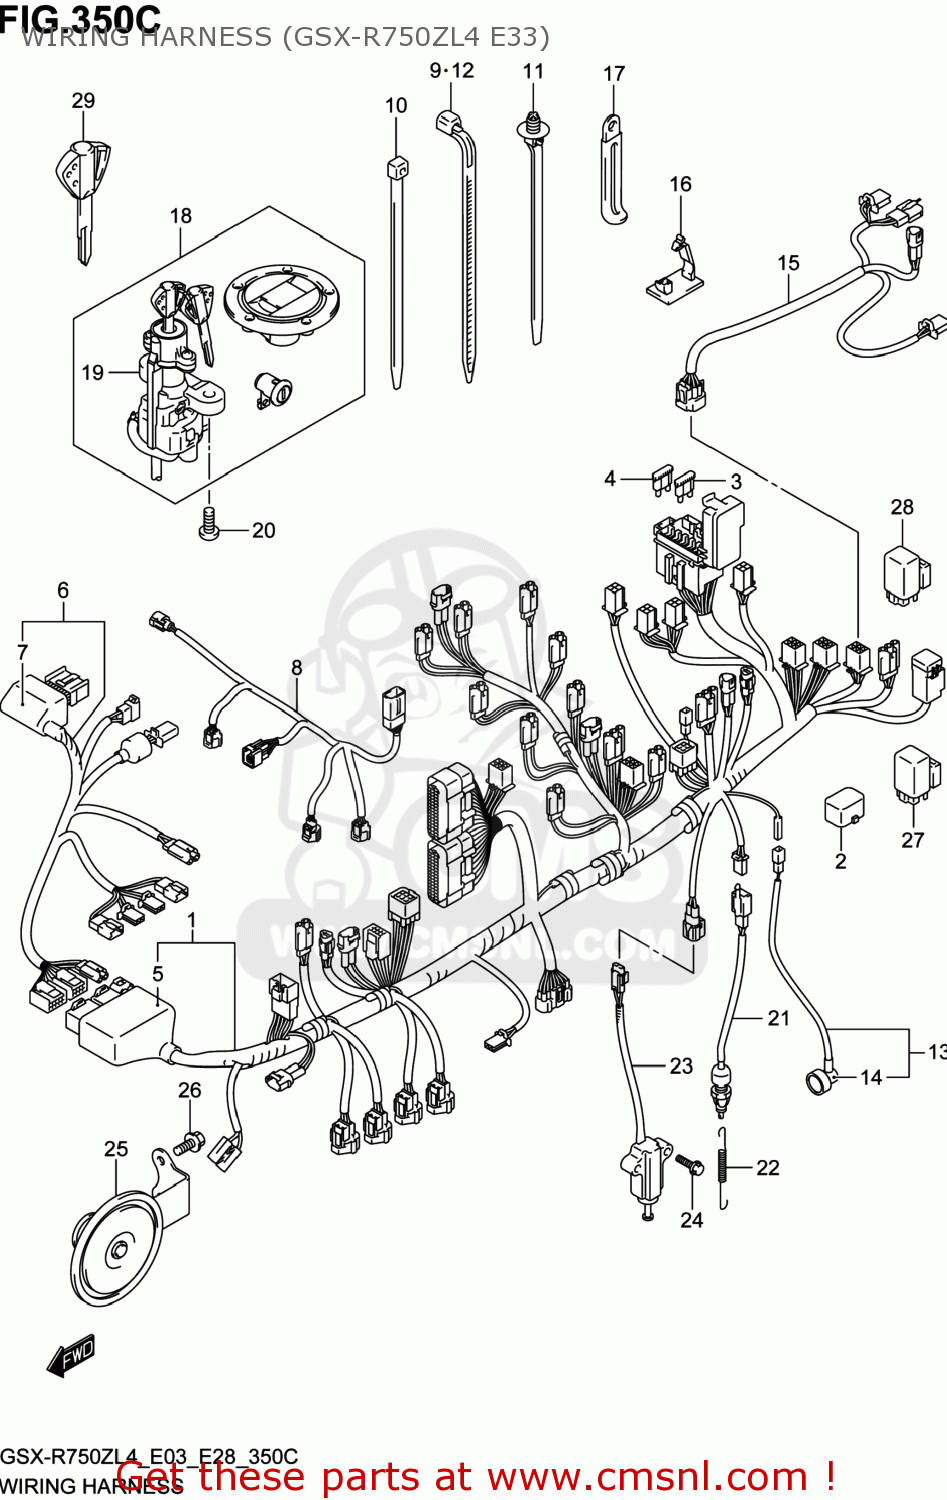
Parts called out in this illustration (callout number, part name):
1	HARNESS,WIRING NO.1
2	CAP,TS
3	FUSE(10A)
4	FUSE(15A)
5	COVER
6	HARNESS,WIRING NO.2
7	COVER,CONNECTOR
8	HARNESS,WIRING NO.3
9	CLAMP(L:95)
10	CLAMP(L:145)
11	CLAMP(L:154)
12	CLAMP(L:125)
13	WIRE,OIL PRESSURE SWITCH LEAD
14	CAP,OIL PRESSURE SWITCH
15	WIRE,RR COMB LEAD
16	CLAMP
17	CLAMP(L:45)
18	LOCK SET
19	LOCK ASSY,STEERING
20	BOLT(8X20)
21	SWITCH ASSY,STOP LAMP
22	SPRING
23	SWITCH ASSY,SIDE STAND
24	BOLT
25	HORN ASSY
26	BOLT
27	RELAY ASSY
28	RELAY ASSY
29	KEY,BLANK(IMMOBII)
